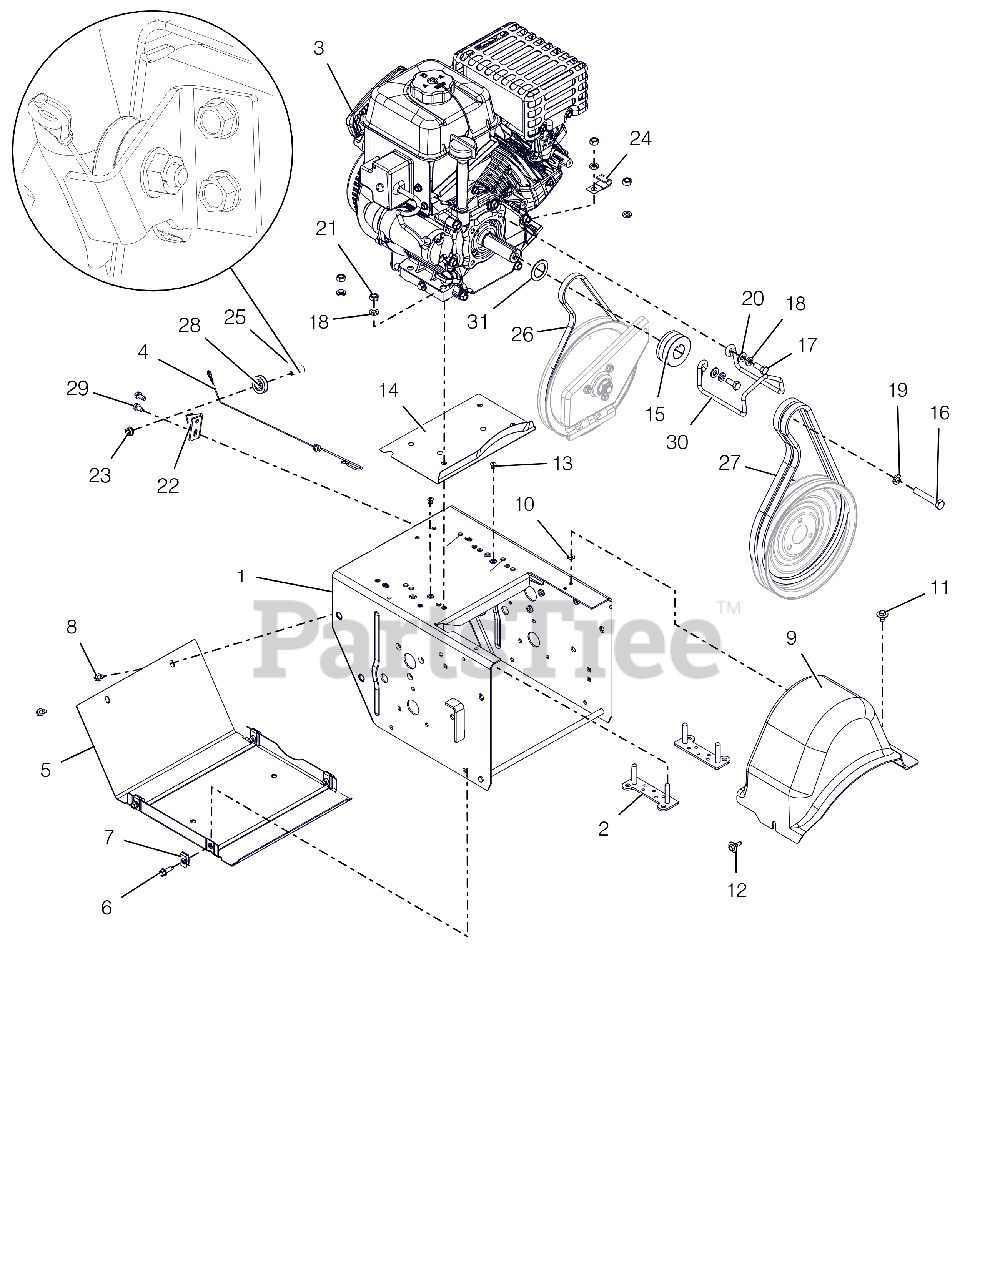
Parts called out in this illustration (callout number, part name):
1	FRAME, MAIN-DELUXE(WELDMENT)
2	STRAP, BOLT - SMALL ENGINE
3	ENGINE, ARIENS AX254 240V/60W
4	CABLE, LOWER TRACTION,SS & PRO
5	COVER, BOTTOM
6	BLT-HEX .25-20X.75 HWH YZ GR5
7	NUT-RTNR .25-20X.56
8	SCR-TAP .25-20X.50 HWH TR YWZ
9	COVER, BELT-SMALL
10	NUT-PUSH .25X.50 O.D.
11	SCR-TAP .25-20X.50 LGHWH TR YZ
12	SCR-TAP .25-20X.5 CAPTIVE
13	RVT-POP .187 YZ
14	BAFFLE, WATER-SMALL
15	SHEAVE, DRIVE
16	BLT-HEX .38-24X2.25 YWZC GR5
17	BLT-HEX .31-24X.75 YWZC GR5
18	WSHR-LK .312X.097 HVY YWZC
19	@WSHR-LK .38X.094 REG YWZC
20	@WSHR-FL-STL.344X.688X.065YWZC
21	@NUT-HEX .31-18 YWZC
22	BRACKET, CABLE PULLEY
23	@NUT-LK-TOP-FLG .25-20 YWZC
24	J-CLAMP
25	BOLT, SHLDR-.375X.375X.25-20
26	V-BELT, 3L-WRAPPED
27	V-BELT, HA-RAW EDGE (SET)
28	PULLEY, CABLE
29	SCR-TAP .25-20X.50 HWH TR YWZ
30	FINGER, BELT
31	WSHR-FL-STL 1.010X1.505X.062YZ
